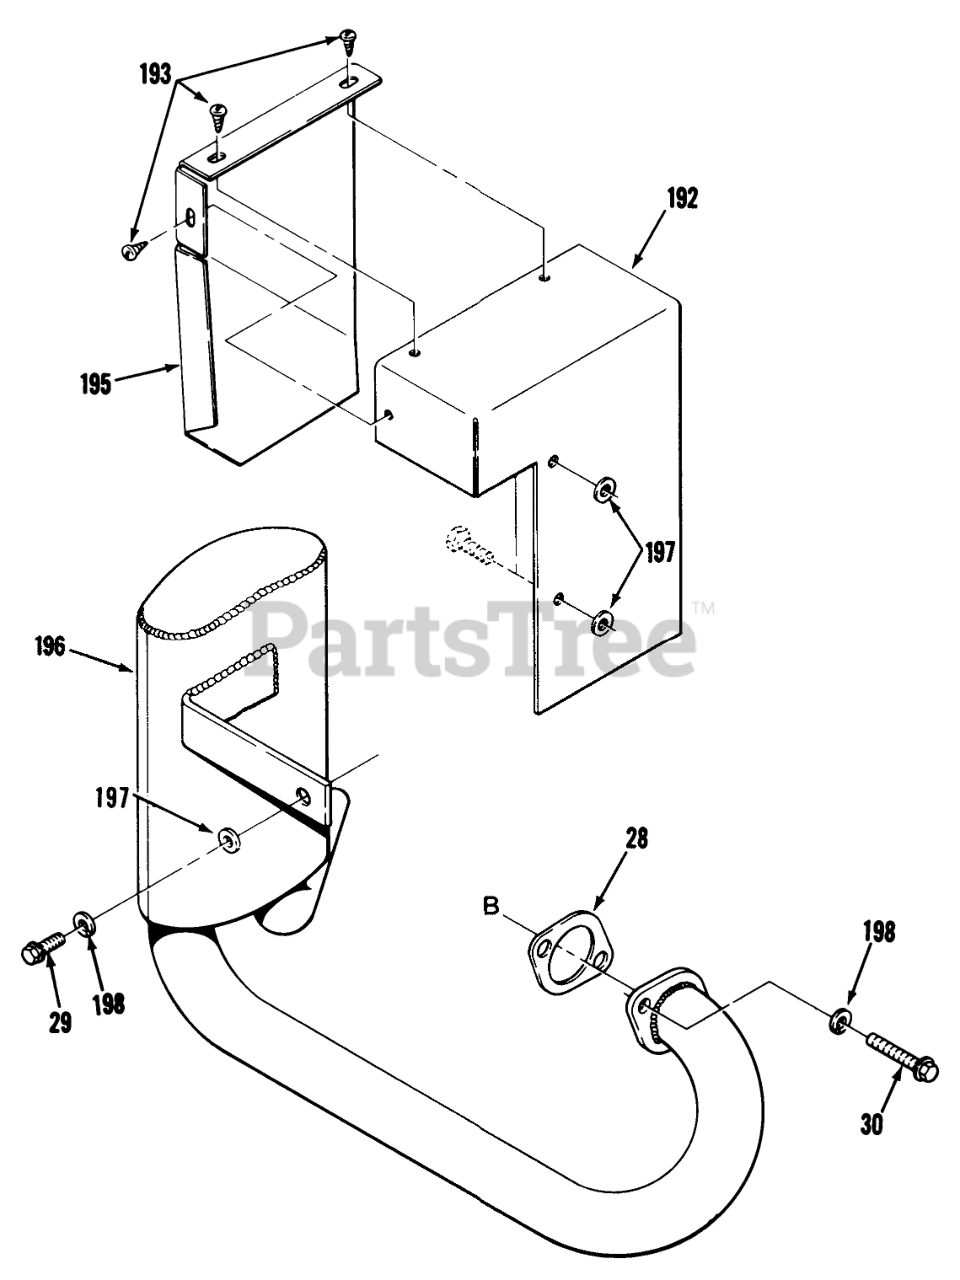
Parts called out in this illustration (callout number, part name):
28	GASKET-L MUFFLER
29	HHCS M8X1.25X15
30	HHCS M8X1.25X20
191	Deflector
192	SHIELD-HEAT B
193	SCRW-HX S.T.#8 X 3/8
195	SHIELD-HEAT
196	Muffler-Black
197	WASHER 5/16 SAE
198	Lockwasher
